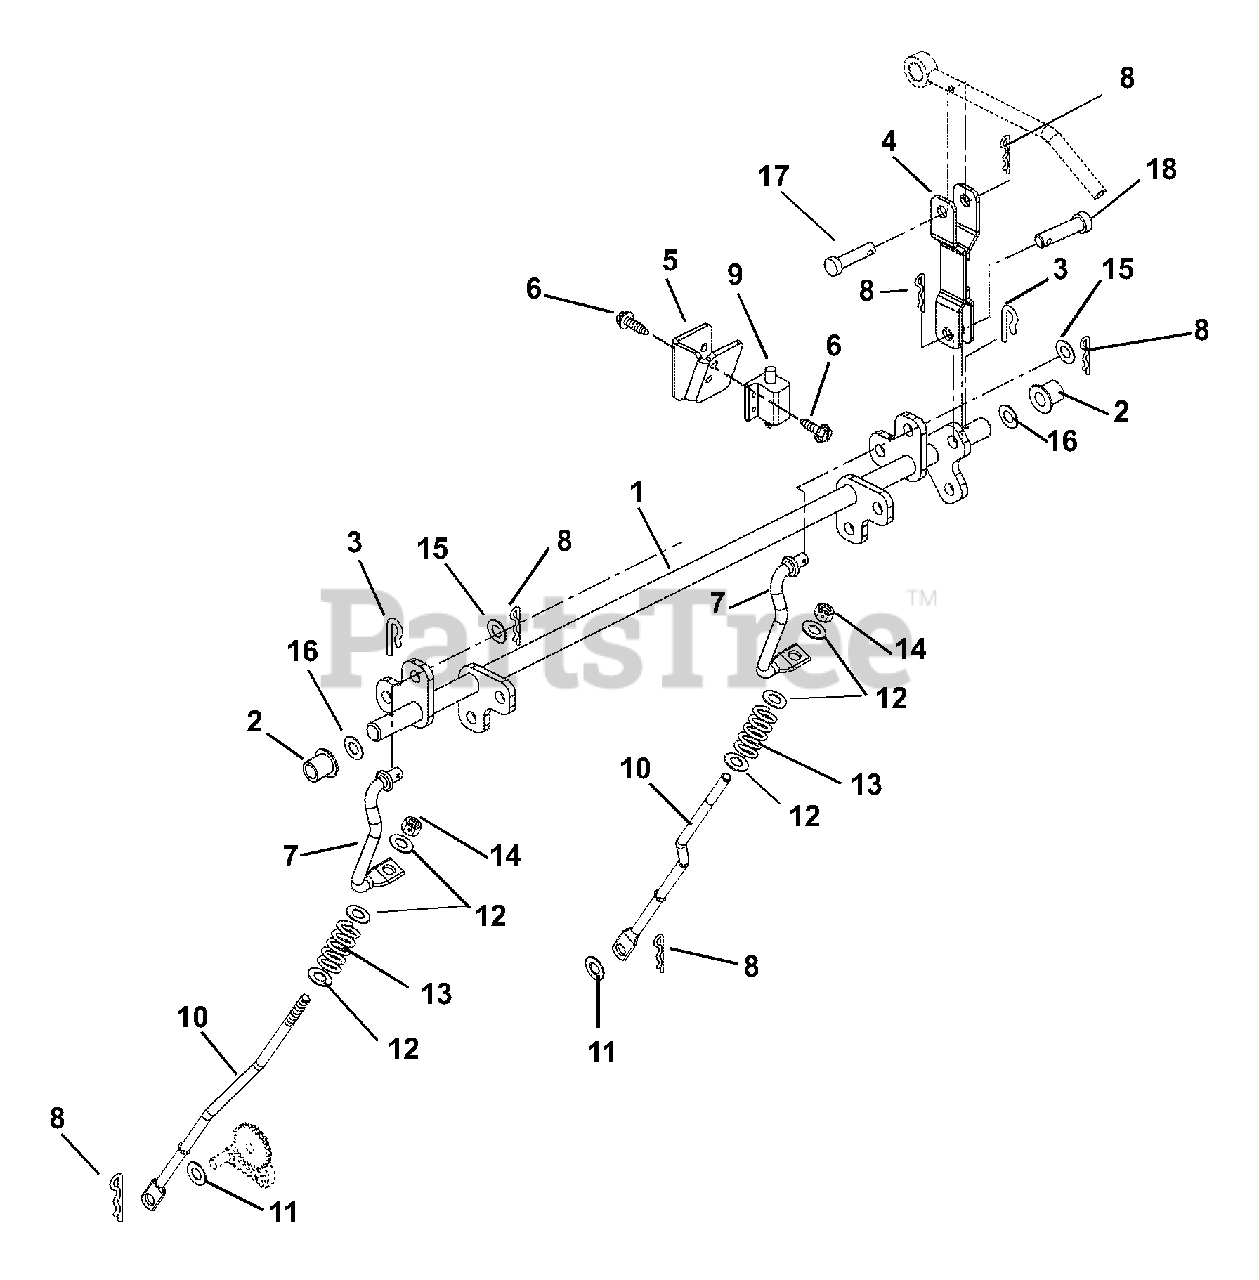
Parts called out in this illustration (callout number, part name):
1	Weldment, Brake Rod
2	Bushing, Flange .63 x 1.00 x .625 Nylon
3	Pin, Spring Clip
4	Clevis Weldment
5	Bracket, Brake Switch
6	Screw, Tapping 10-24 x .50 Hex Washer Head
7	Rod, Over Center
8	Pin, Hair
9	Switch, Double Pole N.O./N.O.
10	Rod, Park Brake IZT
11	Washer, Flat Steel .406 x 1.00 x .188
12	Washer, Flat Steel .344 x .688 x .065
13	Spring, Compression .063 x .53 x 1.187
14	Nut, Locking Nylon .312-18
15	Washer, Flat Steel .406 x .812 x .065
16	Washer, Flat Steel .627 x .99 x .032
17	Pin, Clevis .037 x 1.50
18	Pin, Clevis .375 x .948
